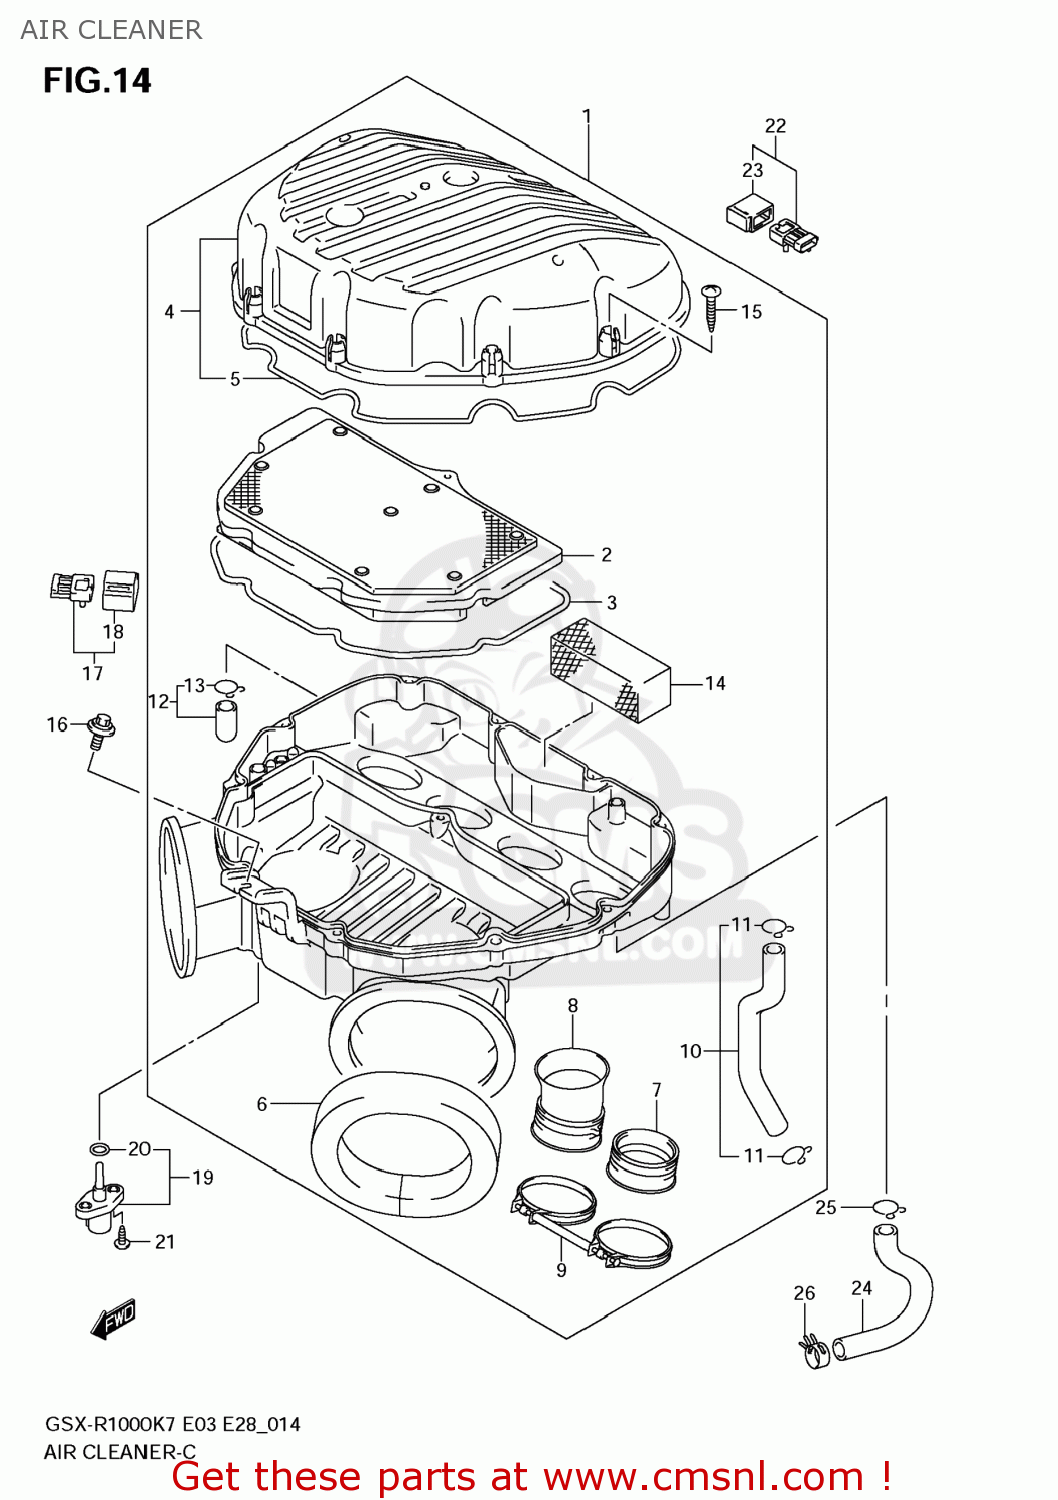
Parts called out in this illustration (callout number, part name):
1	CLEANER ASSY,A
2	FILTER ASSY,AIR CLEANER
3	GASKET,CASE (NAS)
4	CAP,AIR CLEANER
5	GASKET,CAP (NAS)
6	CUSHION,DUCT
7	TUBE,OUTLET A
8	TUBE,OUTLET B
9	CLAMP COMP,INT
10	TUBE,BREATHER
11	CLIP
12	PLUG ASSY,DRAIN
13	CLIP
14	FILTER,BREATHER
15	SCREW
16	BOLT(6X16)
17	SENSOR,BOOST
18	COVER
19	SENSOR,AIR TEMP
20	O RING
21	SCREW
22	SENSOR,AIR PRESSURE
23	COVER
24	HOSE,ISC VALVE
25	CLIP
26	CLIP
